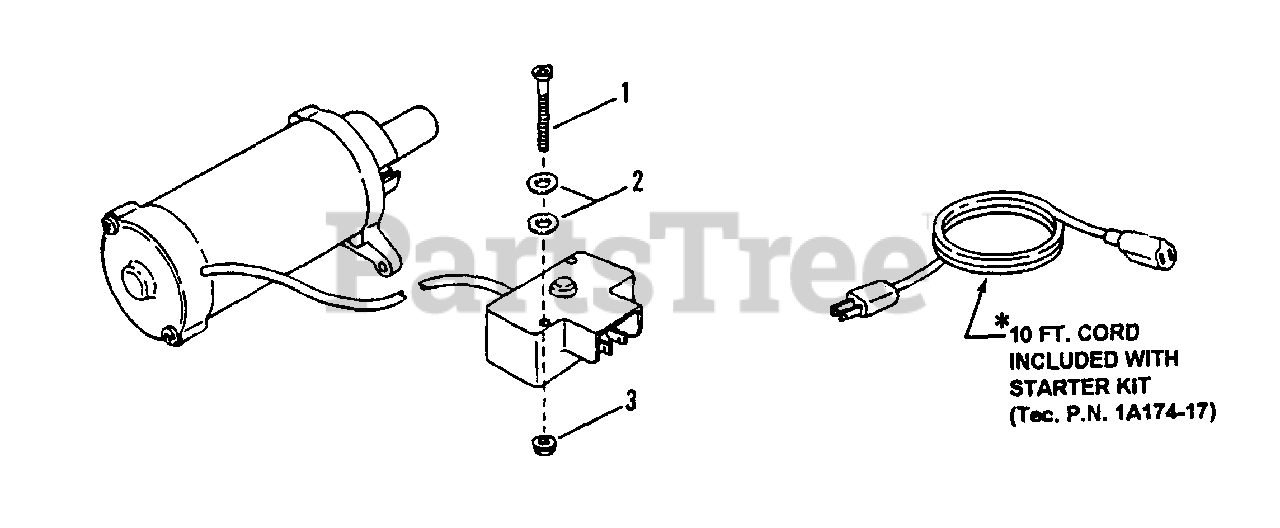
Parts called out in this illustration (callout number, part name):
1	SCREW, #10-24 x 1-3/4" Phillips Pan Head
2	NUT, #10-24 Hex Flange Lock
3	CORD, 10 Foot Extension
